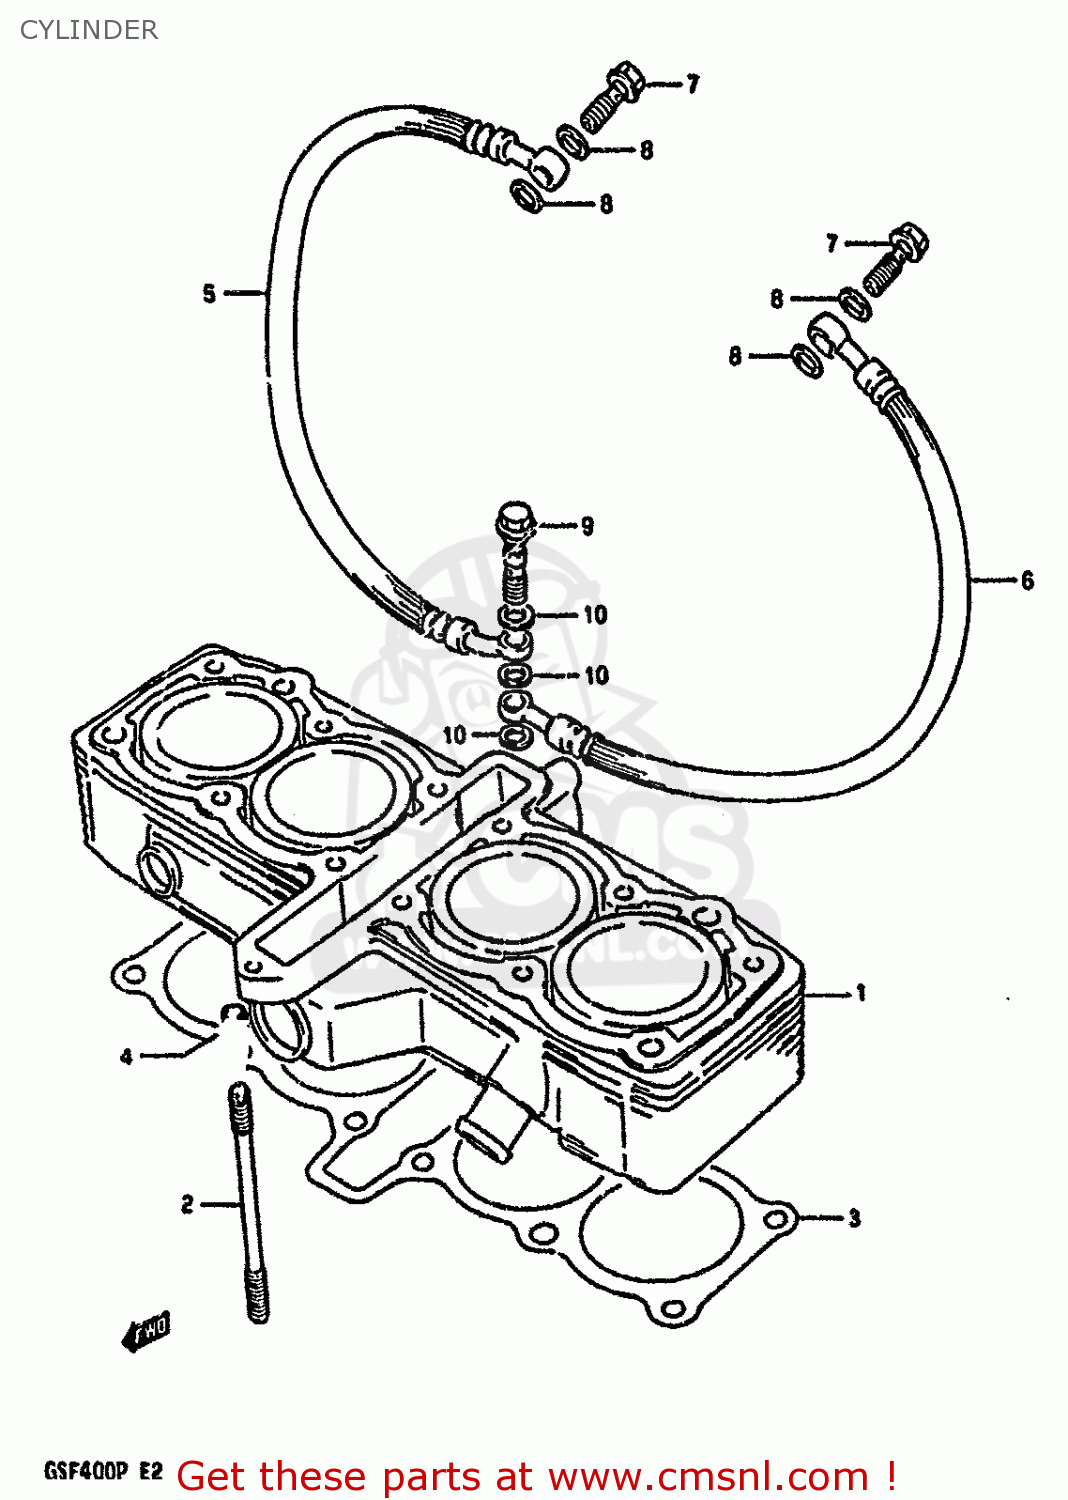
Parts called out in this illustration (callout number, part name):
1	CYLINDER
2	BOLT,STUD(8X120)
3	GASKET,CYLINDER (NAS)
4	PIN
5	HOSE,CRANKCASE OIL,RIGHT
6	HOSE,CRANKCASE OIL,LEFT
7	CLAMP,OIL HOSE CRANKCASE
8	GASKET (NAS)
9	BOLT,OIL PIPE UNION,NO
10	WASHER(10X15X1.5)
